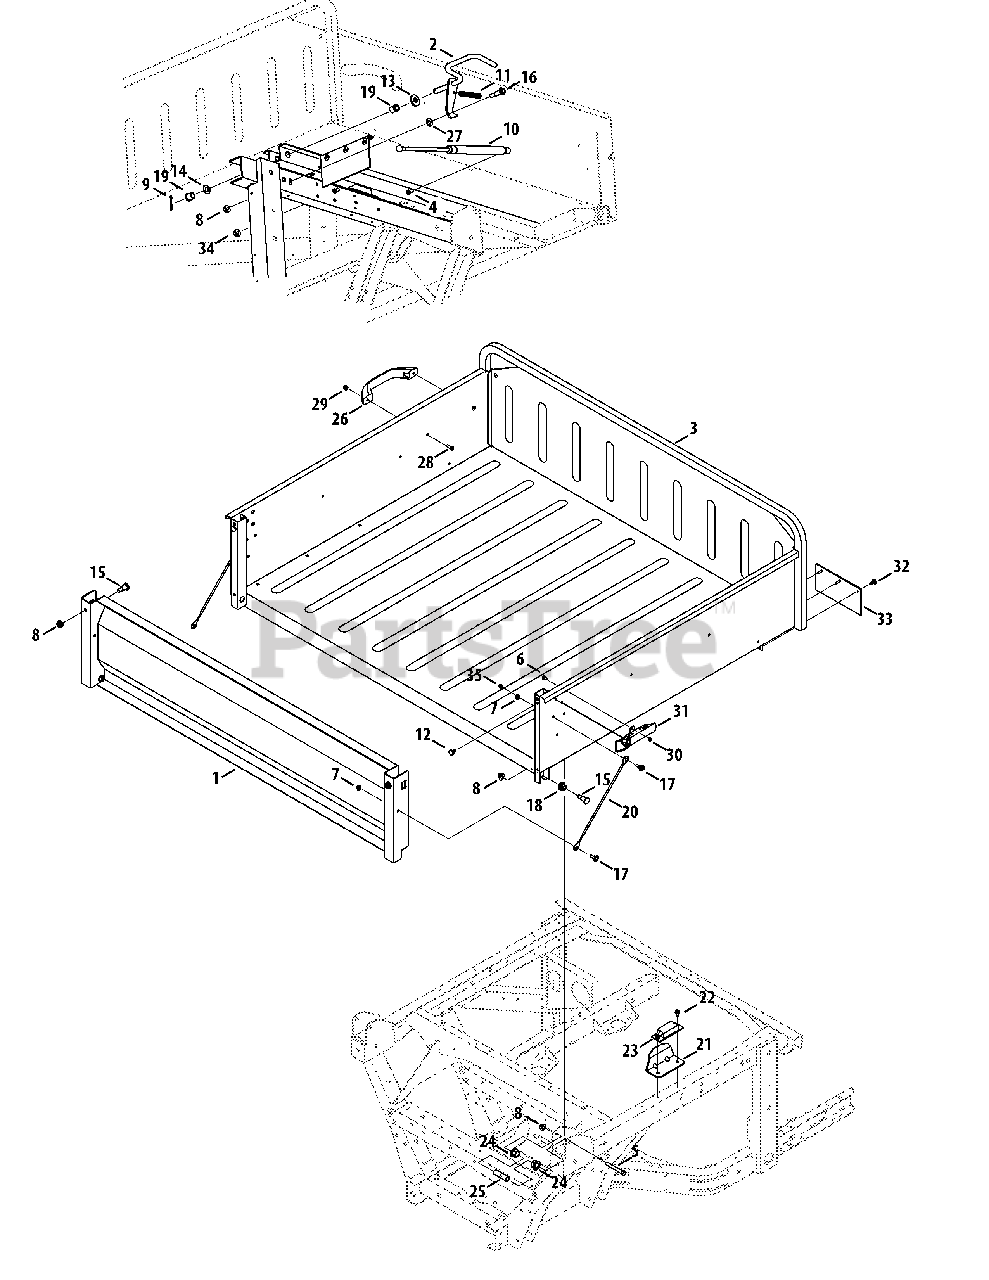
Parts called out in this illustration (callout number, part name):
1	Tailgate Assembly, Red
2	Lever Assembly, bed, latch
3	Box Assembly, bed Red
4	Stud, ball, 5/16-18
5	Screw, 3/8-16, 2.75, gr5, std
6	Screw, machine, 10-24, 0.500
7	Nut, Flange Lock, 1/4-20, nylon
8	Nut, Flange Lock, 3/8-16, nylon
9	Pin, cotter, 5/32, 1.25
10	Spring, gas, 6.91 Stroke
11	Spring, extension, .50 Od x 4.35
12	Bumper, .62 Dia. x .3
13	Washer, flat, .531 x 1.25 x .181
14	Washer, flat, .510 x 1.00 x .060
15	Screw, shoulder, .50 x .685, 3/8-16
16	Screw, shoulder, .50x.925, 3/8-16
17	Screw, shoulder, .375x.280, 1/4-20
18	Bearing, Flange, hex, .506 Id x .590
19	Bearing, Flange, .503 x .689 x .792
20	Cable, lanyard
21	Bracket, Bed Guide
22	Screw, tt, 1/4-20x.625, hxindwsh
23	Bumper, suspension, extension
24	Bearing, hex Flange .629 Id
25	Spacer, .390 Id x.625 Od x2.03 Lg
27	Washer, Flat, .385 x .870 x .092
28	Screw, Mach., 1/4-20 x .750
29	Nut, Hex Lock., 1/4-20
30	Nut, Hex Lock, #10-24
31	Latch, draw, over Center
32	Pop Rivet, .188 dia, 37-50 grip
33	Rear Mud Flap
34	Nut, Flange Lock, 5/16-18, nylon
35	Nut, Acorn, 1/4-20
